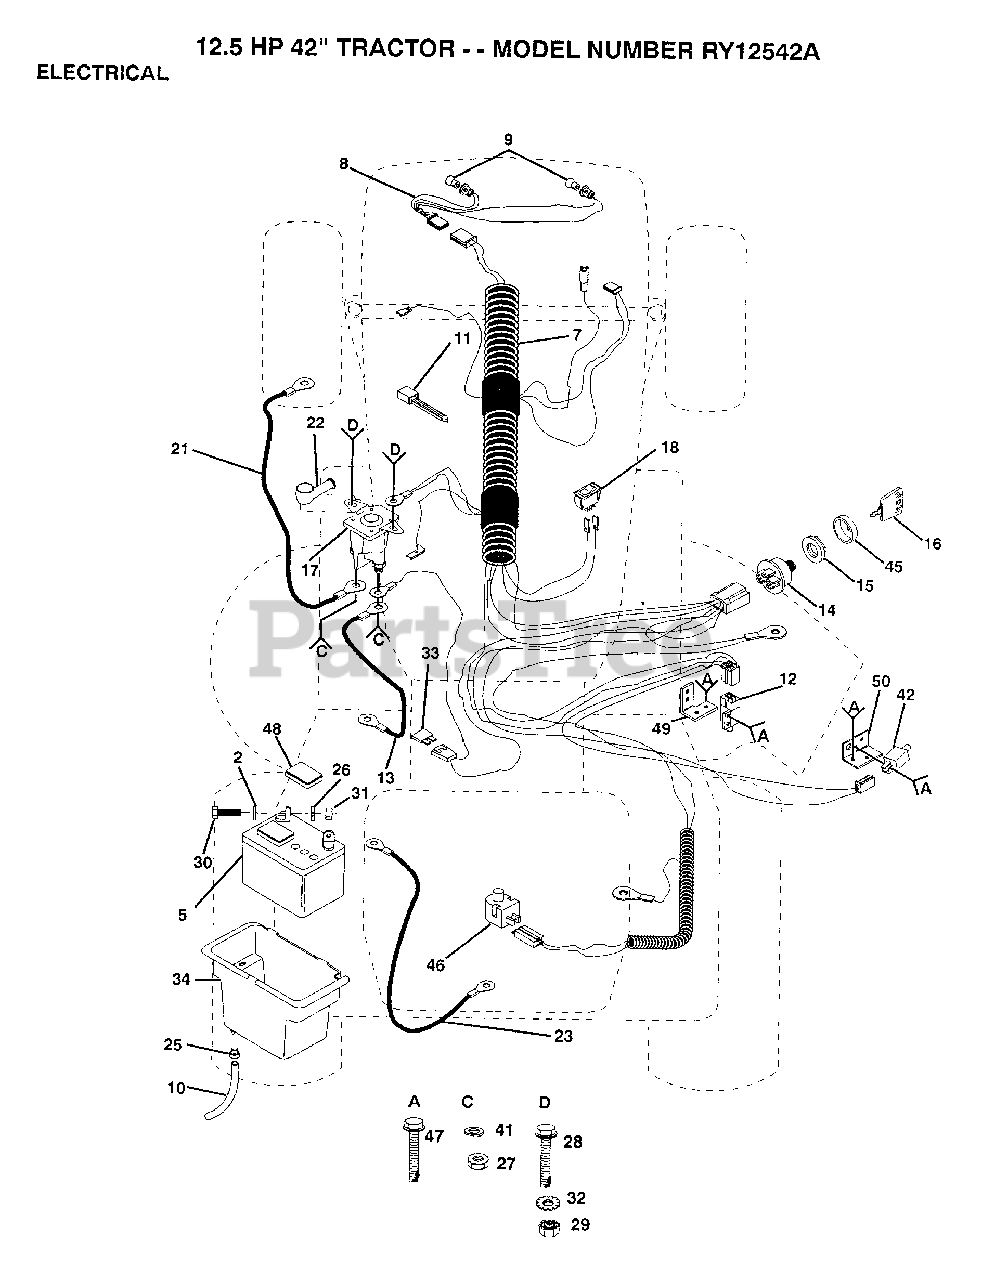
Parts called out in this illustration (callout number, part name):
2	WASHER
11	WIRE TIE
12	SWITCH INTERLOCKT
13	STARTER CABLE GT
15	NUT IGNITION
16	KEY
18	SWITCH LT
21	"CABLE T, BATTERY"
23	CABLE T
25	HOSE CLAMP T
26	LOCKWASHER
27	NUT
28	BOLT
29	NUT
30	BOLT LT
33	FUSE HYT
34	BTRY CASE W/O LID
42	SWITCH-INTER. GT
46	SWITCH SEAT
47	SCREW
48	"CAP,BATTERY "
49	SWITCH BRACKET
50	BRACKET LT
